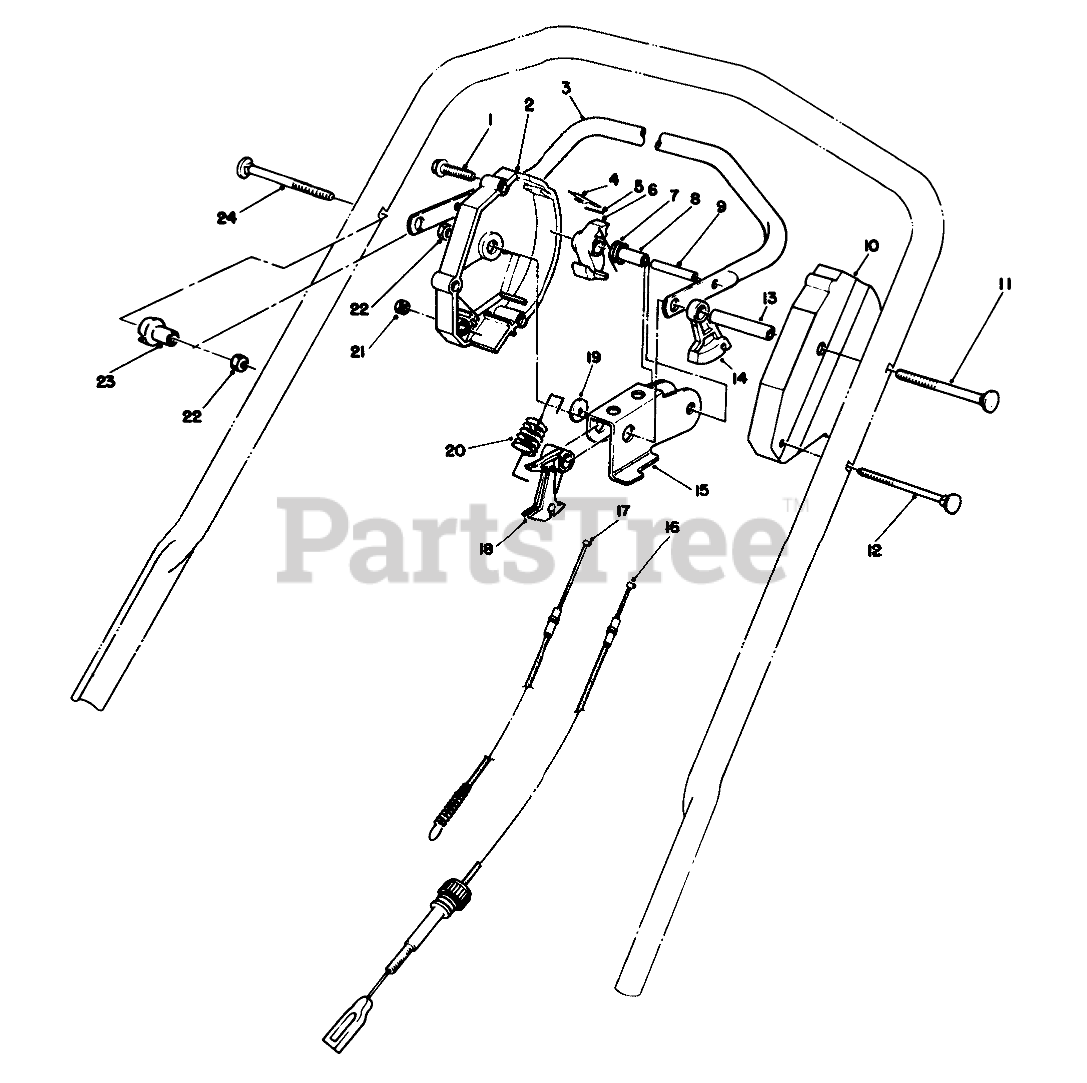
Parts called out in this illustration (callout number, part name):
1	SCREW-HWHTF
2	RH CONTROL HOUSING ASM
3	Bar-Control
4	SPRING-LEAF
5	PIN-INSERT
6	HOOK-CONTROL
7	SPRING-TORSION
8	SPACER
9	PIN-ROLL, SLOTTED
10	HOUSING-CONTROL, LH
11	5/16-18 X 3 HNDLE SCREW
12	HANDLE SCREW
13	TUBING-SPACER
14	LEVER-TRACTION
15	ROCKER
16	TRACTION CABLE
17	Cable-Clutch
18	LEVER-CABLE
19	PLASTIC WASHER
20	DETENT SPRING
21	NUT-HEX
22	NUT-LOCK, NI
23	SPACER-SUPPORT
24	5/16-18 X 2 HNDLE SCREW
